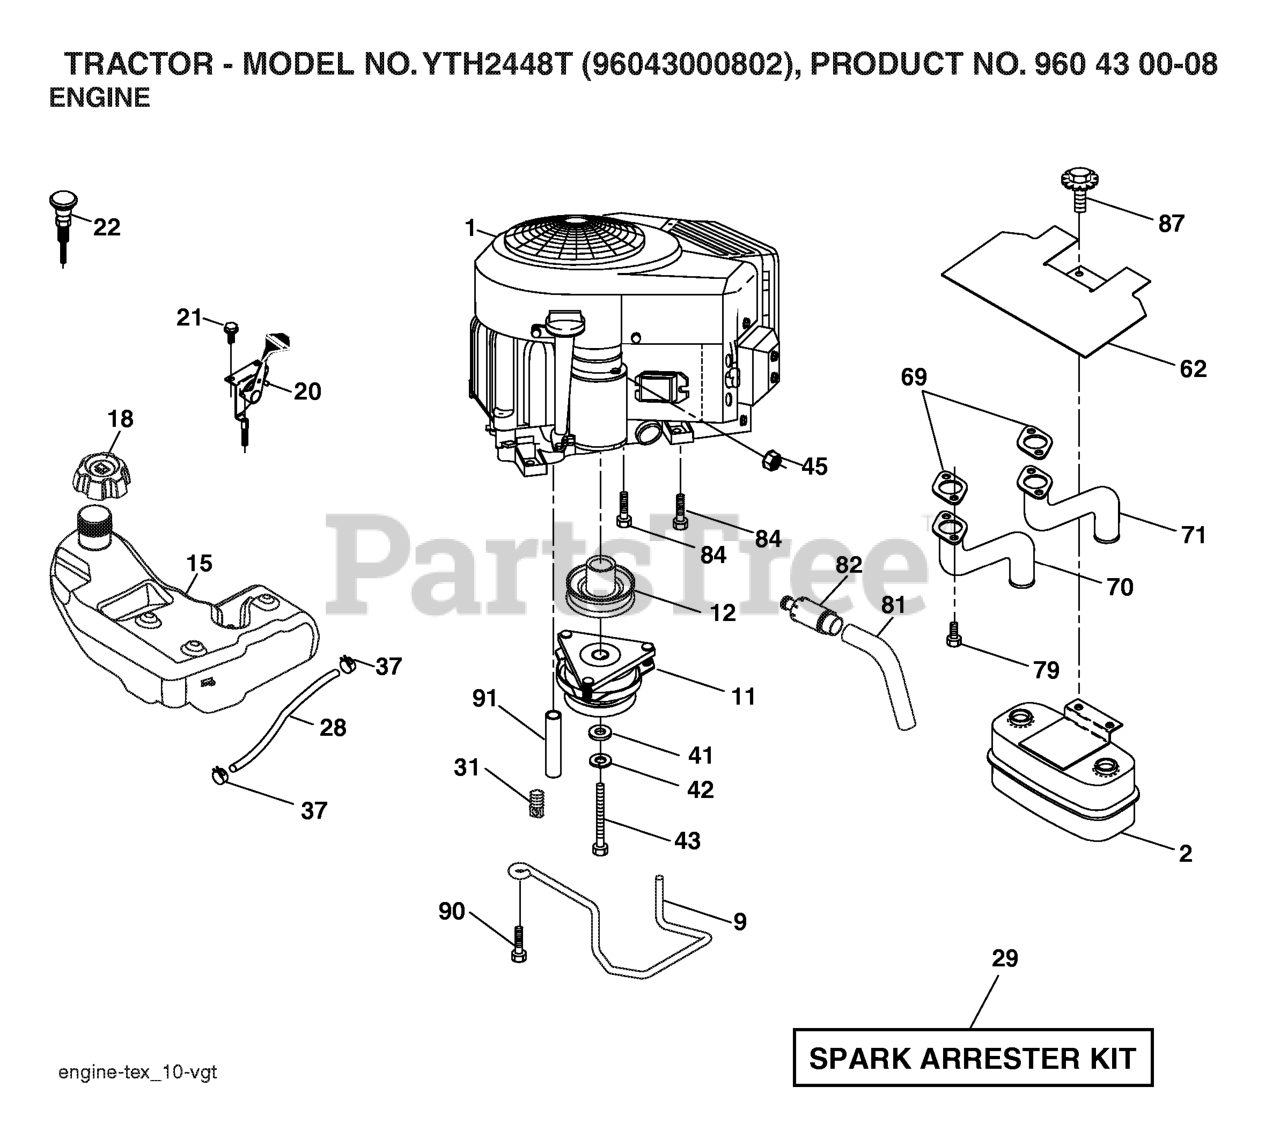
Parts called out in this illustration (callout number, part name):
2	MUFFLER.TWIN.CYL.LOW.TONE
9	KEEPER.BELT.ENGINE.4.2
11	CLUTCH ELECTRIC
12	PULLEY.ENGINE.TUFFTORQ
15	TANK.FUEL.4GAL
18	CAP.FUEL.TANK.3"GREY
20	THROTTLE CABLE
21	SCREW
22	CONTROL.CHOKE.ERGO.PUSH-IN.BLA
29	KIT.SPARK ARRESTOR 794945 B&S
37	HOSE CLAMP
42	LOCKWASHER
43	BOLT HEX
45	NUT
62	RP SHIELD HEAT MUFFLER
69	GASKET.MUFFLER
70	RP.EXHAUST.TUBE.LH.BS/TWIN
71	EXHAUST.TUBE.RH.BS/TWIN
79	SCREW.SOCKET.HEAD.5/16-18
81	TUBE, DRAIN OIL ASM.
82	PLUG DRAIN OIL EASY
84	SCREW.3/8-16
87	BOLT.5/16-18UNCX1.W/SEMS.BLK
90	SCREW 3/8-16X1
91	BUSHING.1.375OD
